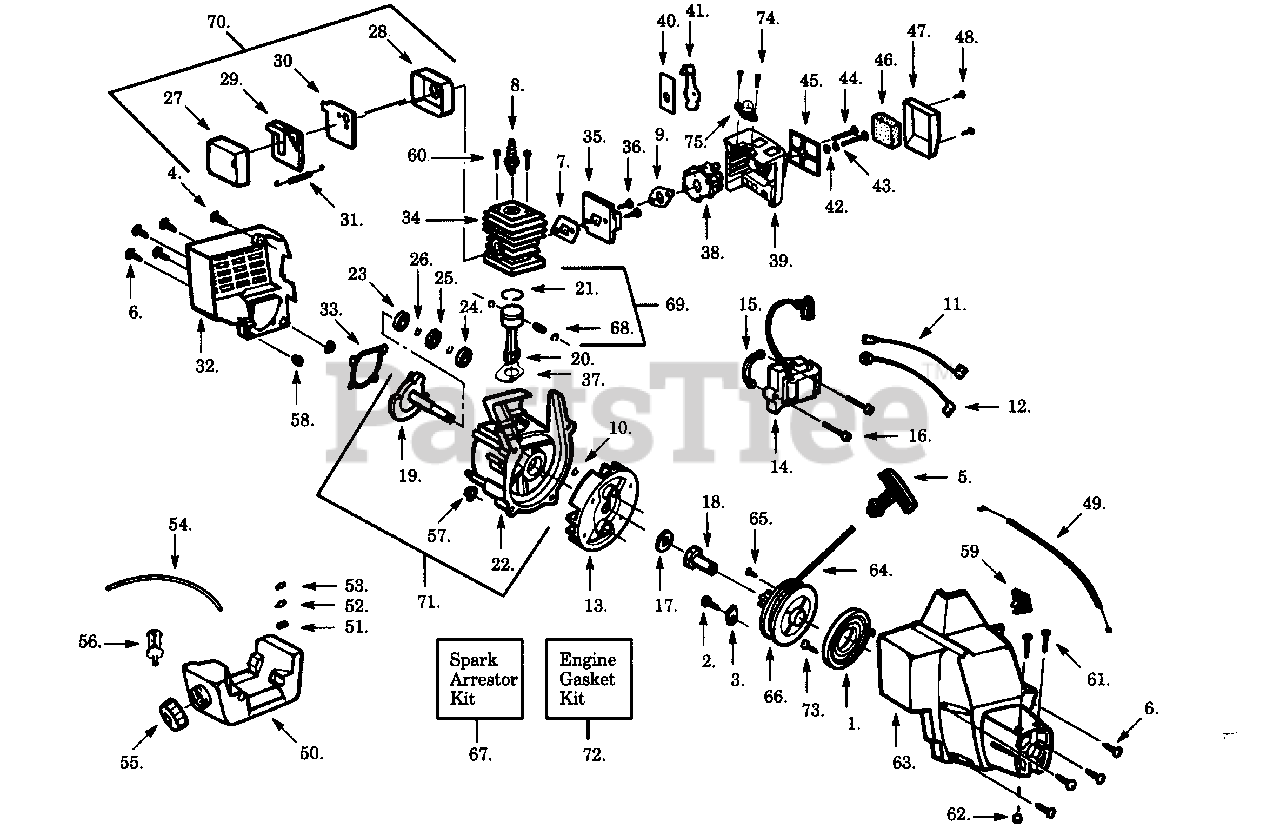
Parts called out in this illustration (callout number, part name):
1	Starter Spring
3	Retainer
5	Starter Handle
6	Screw
7	Cylinder Gasket
8	Spark Plug
10	Retainer
11	Lead Wire
12	Ground Wire
13	Flywheel Ass'y.
14	Ignition Module
18	Drive Coupling
19	Crankshaft Ass'y.
20	Connecting Rod Ass'y.
21	Piston Ring
22	Crankcase Ass'y.
23	Inner Bearing
24	Outer Bearing
25	C'case Seal
26	Retaining Ring
27	Muffler Body
28	Muffler Cover
29	Muffler Baffle-Exit
30	Muffler Baffle-First
31	Muffler Spring
34	Cylinder
37	Gasket
38	Type I (WA-215)
38	Type II (WA-218)
41	Choke Shutter
42	Wave Washer
43	Choke Spacer
49	Throttle Cable Ass'y.
51	Check Valve
53	Retainer
54	Fuel Line
54	Return Line
55	Fuel Cap Ass'y.
56	Fuel Pickup Ass'y.
57	C'case Isolator
58	Shroud Isolator
59	On/Off (Old style)
59	Momentary(New style)
64	Rope Kit
65	Screw
66	Starter Pulley
67	Spark Arrestor Kit
68	Piston Pin Retainer
69	Piston Kit (Inc. 21,68 & Pin)
70	Muffler Kit
71	C'case & C'shaft Assy (Inc. 10,19, 22-26)
72	Engine Gasket Kit (Inc. 7, 9, 33, 37)
74	Bulb Ass'y.-Type II
75	Screw-Type II
